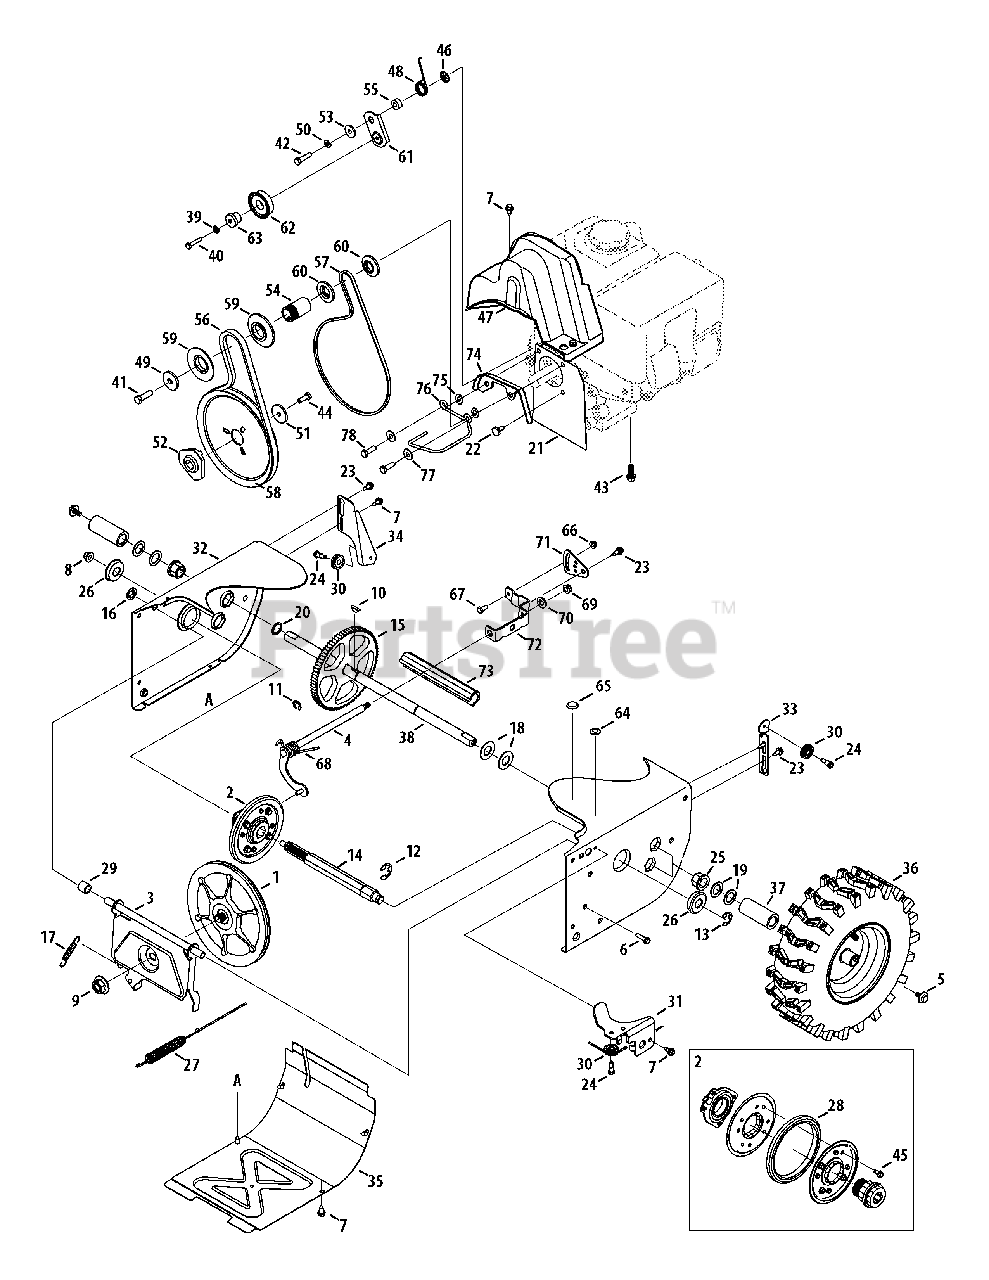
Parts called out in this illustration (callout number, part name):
1	Disc Assembly, Friction Wheel
2	Friction Wheel Assembly, 5.5 OD
3	Support Bracket, Friction Wheel
4	Shift Assembly, Rod
5	Screw, 5/16-24, .750, Gr5
6	Screw, 1/4-20, 1.000
7	Screw, 1/4-20 x .625
8	Nut, Flange Lock, 3/8-16, Nylon
9	Nut, Flange, 5/8-18
10	Key, Hi Pro, 3/16 x 3/4 Dia.
11	E-ring, .500 Dia.
12	E-ring, Retaining, .875 Dia.
13	E-ring, .750 Dia.
14	Hex Shaft, .8125, 7-Tooth
15	Gear, 80-Tooth
16	Speed Nut, .500
17	Extension Spring
18	Washer, Flat, .760 x 1.490 x .060
19	Washer, Flat, .793 x 1.24 x .060
20	Washer, Flat, .75 x 1.00 x .060
21	Plate, Cover
22	Shoulder Screw
23	Screw, Shoulder, .37 x .105, 1/4-20
24	Screw, 1/4-28, .375
25	Bearing, Hex Flange x .75 ID
26	Bearing, Ball, 17 x 40 x 12
27	Clutch Cable, Wheel, 44.95"
28	Rubber, Friction Wheel, 5.5 OD
29	Spacer, .508 ID x .75 OD x .68
30	Roller, Cable
31	Front Guide Bracket, Auger Cable
32	Frame
33	Guide Bracket, Auger Cable
34	Guide Bracket, Drive Cable
35	Cover, Frame
36	LH Wheel Assembly
36	RH Wheel Assembly
37	Spacer, 1.25 x .75 x 3.0
38	Axle, .75 x 22"
39	Washer, Lock, 1/4
40	Hex Screw, 1/4-20, 1.25, Gr5
41	Hex Screw, 3/8-24, 1.25, Gr8
42	Hex Screw, 5/16-24, 1.25, Gr5
43	Screw, Sems, 3/8-16, 1.00
44	Hex Screw, 5/16-24, .875, Gr8
45	Screw, 5/16-18 x .750
46	Nut, Push-on, .25 Dia.
47	Cover, Belt
48	Spring, Torsion, .850 ID x .354
49	Washer, Flat, .45 x 1.5 x .172
50	Washer, Lock .3125
51	Washer, Flat, .34 x 1.50 x .150
52	Pulley, Adapter, .75 Dia.
53	Spacer, Shoulder, .317 x .50 x .102
54	Spacer, .875 ID x 1.185 OD
55	Spacer, .340 x .750 x .360
56	Belt, Auger Drive
57	Belt, Wheel Drive
58	Pulley, Auger Drive, 8.1 x .5
59	Pulley, Half, V x 2.600 OD
60	Pulley, Half, 3/8-V x 1.7160 OD
61	Idler Bracket, Wheel Drive
62	Idler Pulley Assembly
63	Spacer, Shoulder, .26 x .79 x .538
64	Plug, 3/8 ID
65	Plug, 1/2 ID
66	Nut, Flange Lock, 1/4-20, Nylon
67	Hex Screw, 1/4-20, .620, Gr5
68	Spring, Torsion, .750 ID x .968
69	Nut, Flange Lock, 5/16-18, Nylon
70	Wash., Flat, .469 x .875 x .105
71	Pivot Bracket, Speed Selector
72	Shift Bracket, Speed Selector
73	Spacer, Axle
74	Belt Cover
75	Washer, Flat, .330 x .687 x .030
76	Belt Guide
77	Flat Washer, .349 x .879 x .063
78	Screw, 5/16-24 x 1.00
